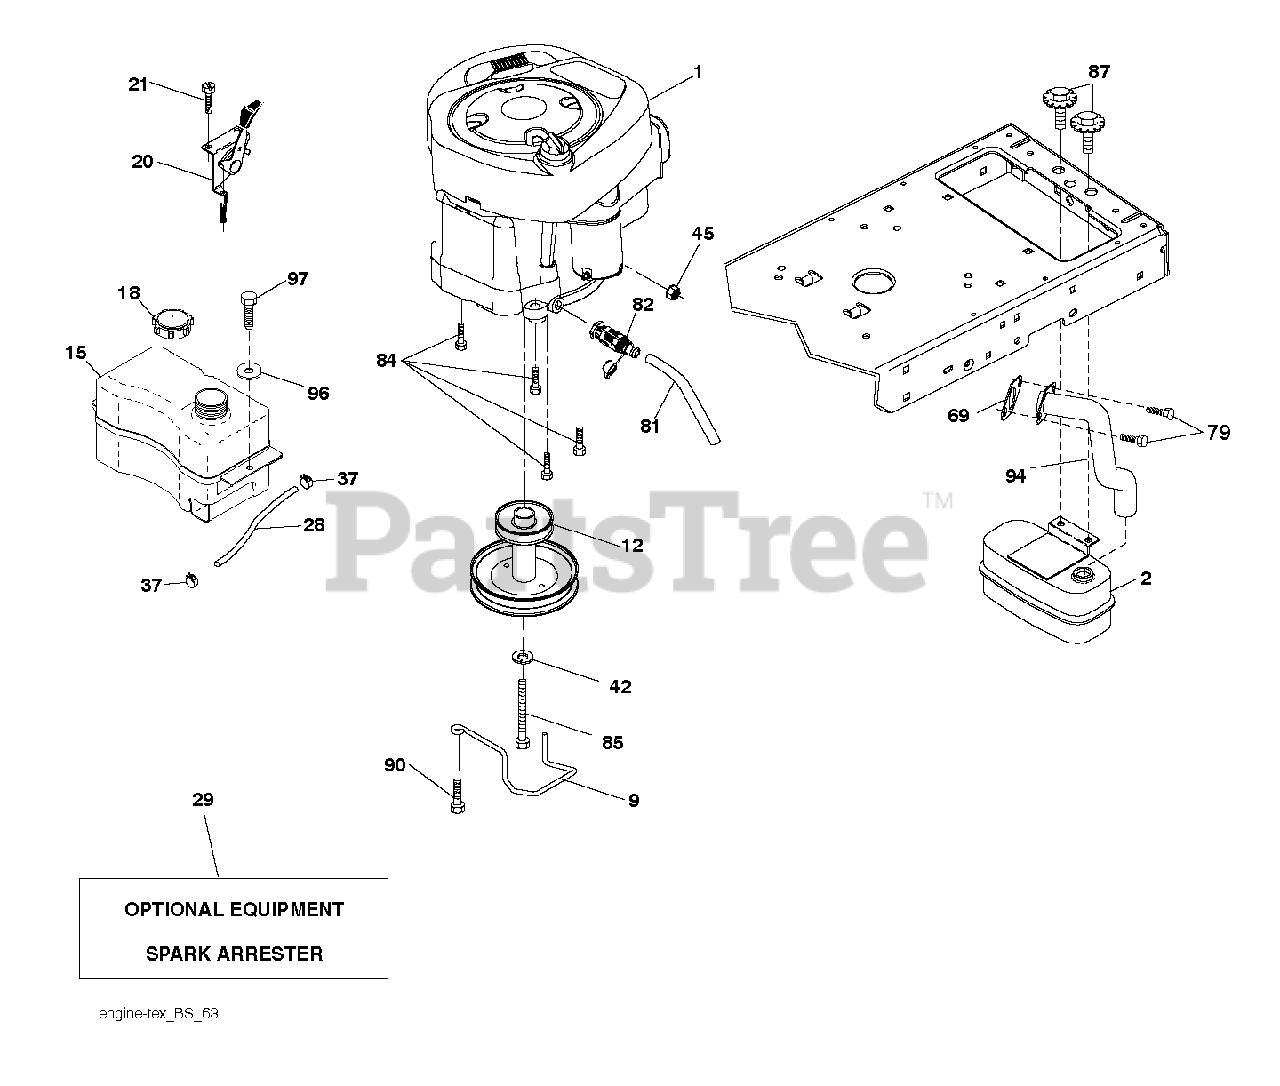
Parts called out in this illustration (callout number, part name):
2	MUFFLER.SINGLE.CYL.KOHL/B&S
9	KEEPER.BELT.ENGINE.3.25
12	PULLEY ENGINE
15	RP TANK FUEL FRT 1.5 GAL
18	CAP ASM.FUEL.2.25"FR.
21	SCREW.#10 X 0.750.BOS (2 2)
28	LINE.FUEL.20"FRONT.EMI
29	SPARK ARRESTOR KIT
37	HOSE CLAMP
42	LOCKWASHER
45	NUT
79	SCREW.SOCKET HD.5/16-1
81	TUBE, DRAIN OIL ASM.
82	VALUE.OIL.DRAIN
84	SCREW.3/8-16
85	BOLT HEX 7/16-20X4-1/4"
87	BOLT, 5/16-18 X 1 3/4
90	SCREW 3/8-16X1
94	EXHAUST.TUBE.B&S.
97	SCREW HEXWSHR 1/4-20X3/4
